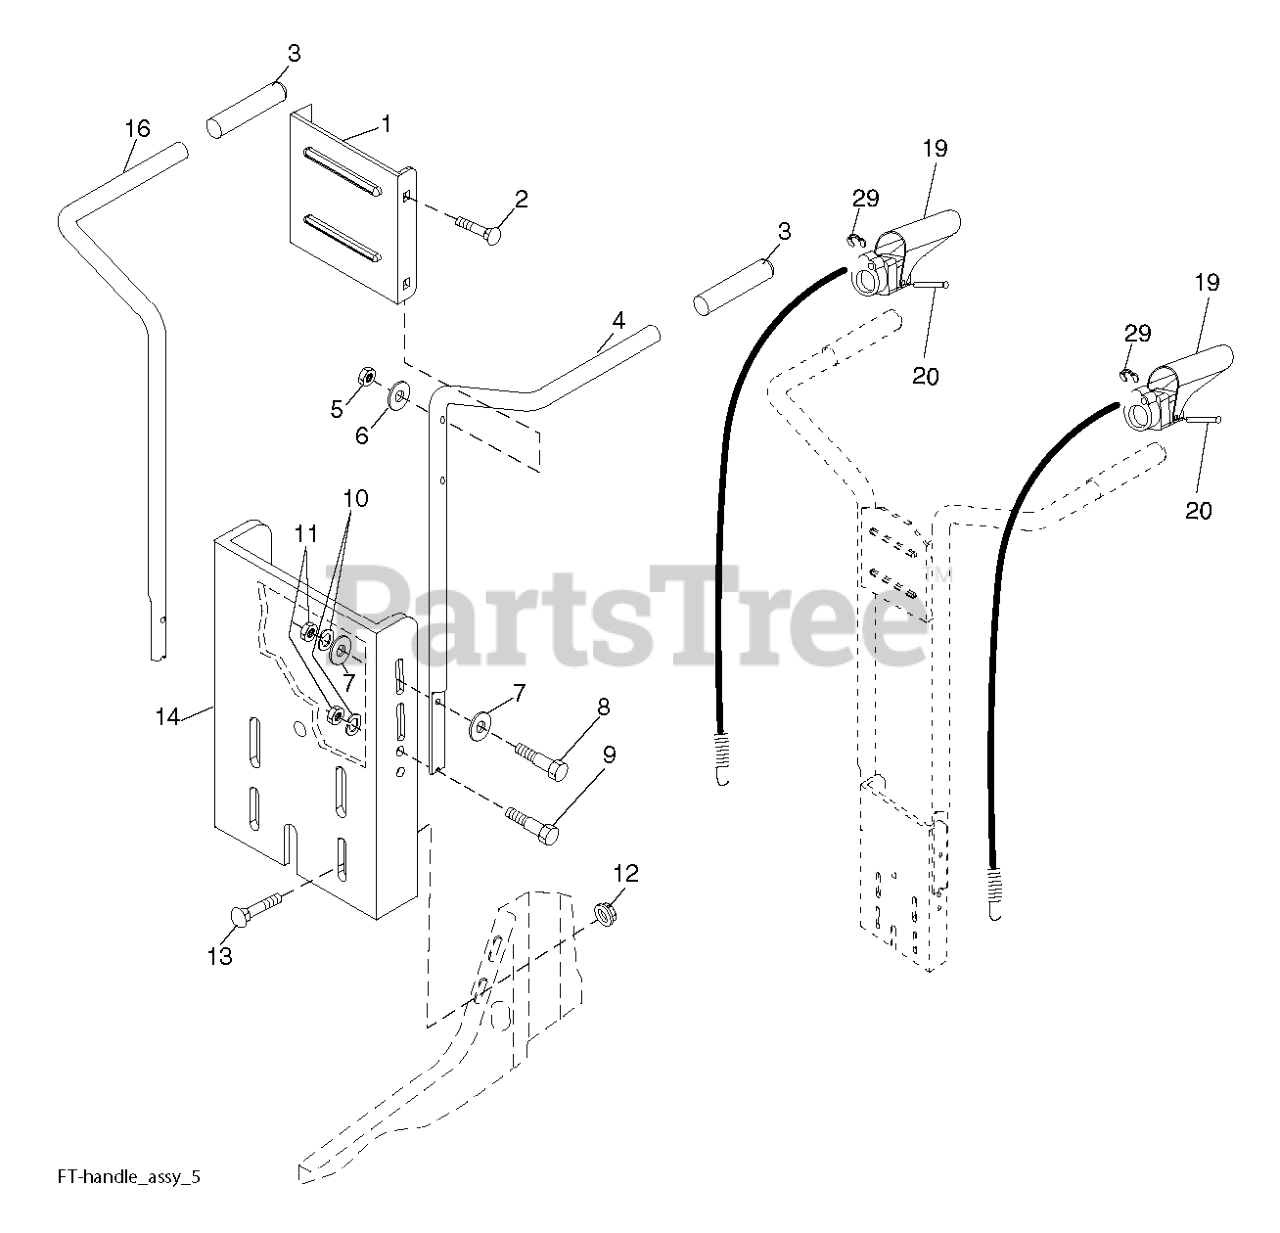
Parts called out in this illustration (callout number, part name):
1	BRACKET.HANDLE.ORANGE
2	BOLT
3	GRIP.HANDLE.BLACK
4	HANDLE.PNT.LH.DOUBLE.BEND
5	LOCKNUT
6	WASHER
7	WASHER.5/16.FLAT.STE.STD.
8	BOLT
9	BOLT RB
10	WASHER.LOCK.HVY.HLCL.SPR.5/16
11	NUT
12	NUT
13	BOLT, RDHD SQNK 5/16-18 X 3/4
14	RP PANEL.PNT.HANDLE.ORANGE.
16	HANDLE.PNT.RH.DOUBLE.BEND
19	CONTROL ASM.TINE.49.88
20	PIN, PIVOT
29	RETAINING.RING.#5103-25
